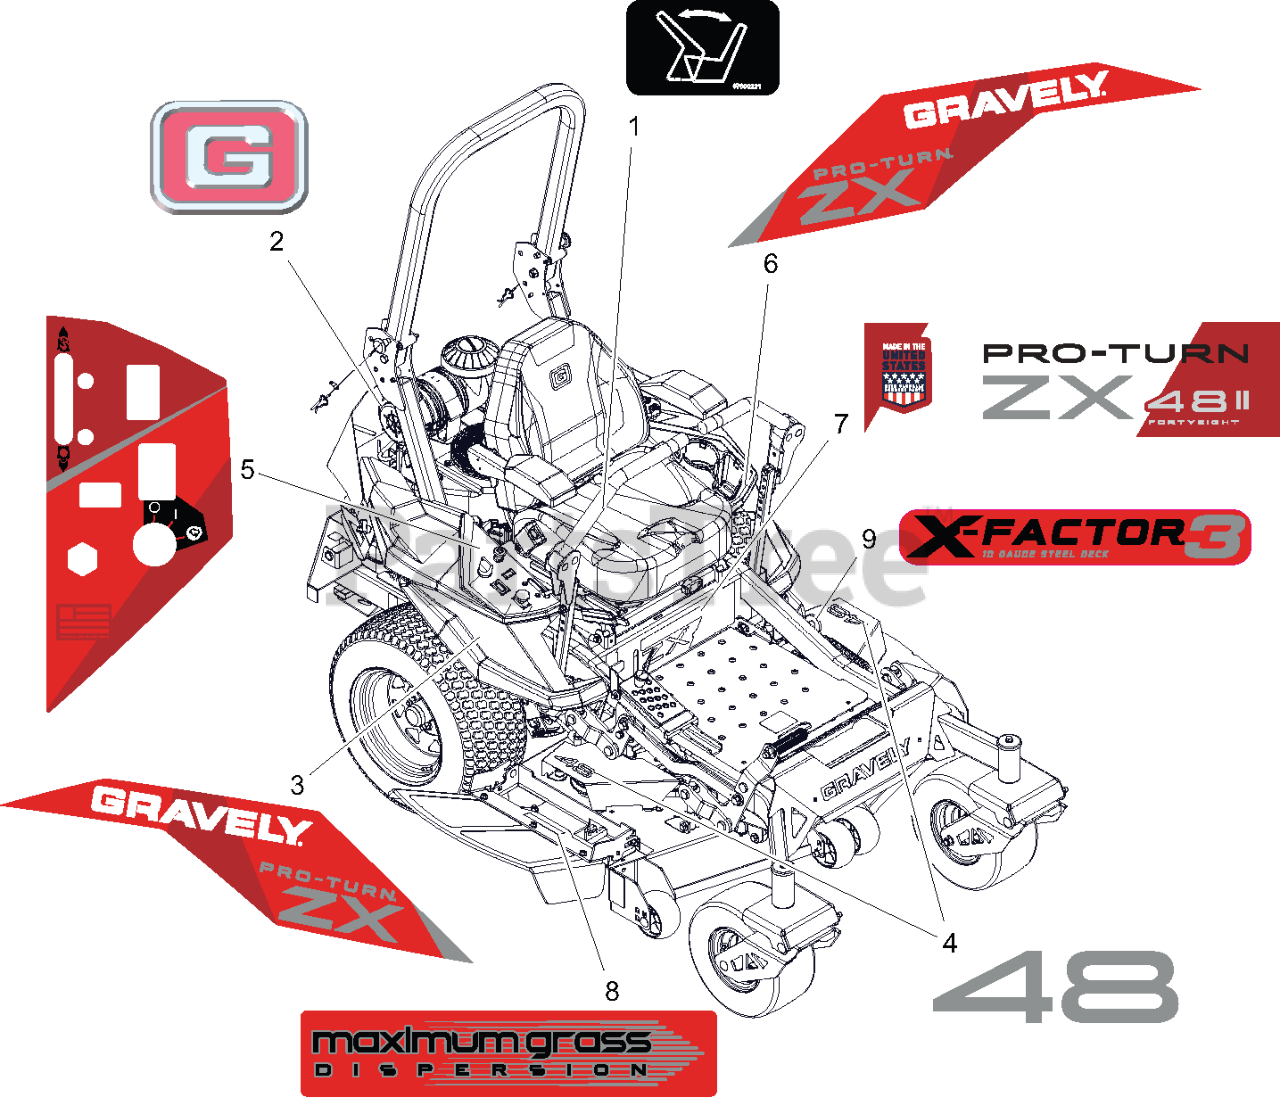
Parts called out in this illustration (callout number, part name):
1	DECAL - SEAT RELEASE
2	DECAL, GRAVELY BRAND
3	DECAL, FENDER RH - PTZX
4	DECAL, DECK - 48
5	DECAL, CONTROL PANEL
6	DECAL, FENDER LH - PTZX
7	DECAL, PTZX -48
8	DECAL, DECK - MAX GRASS
9	DECAL, X-FACTOR 3
